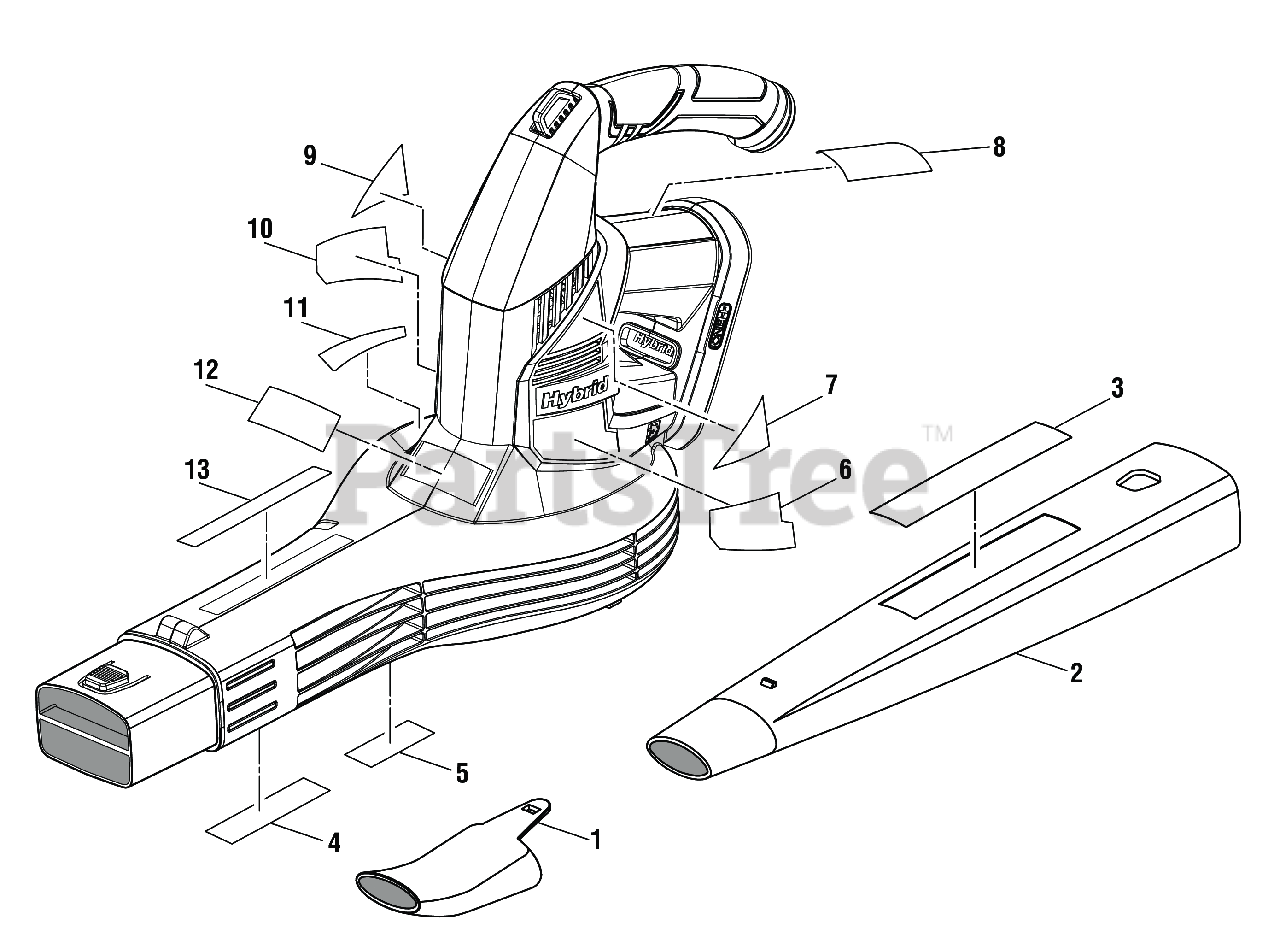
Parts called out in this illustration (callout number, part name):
1	High Velocity Nozzle
2	Blower Tube
3	Blower Tube Logo Label
4	Warning Label (French/Spanish)
5	Data Label
6	Left Bottom Label
7	Left Top Label
8	Hybrid Icon Label
9	Right Top Label
10	Right Bottom Label
11	Warning Label (English)
12	Logo Label
13	Warning Icon Label
